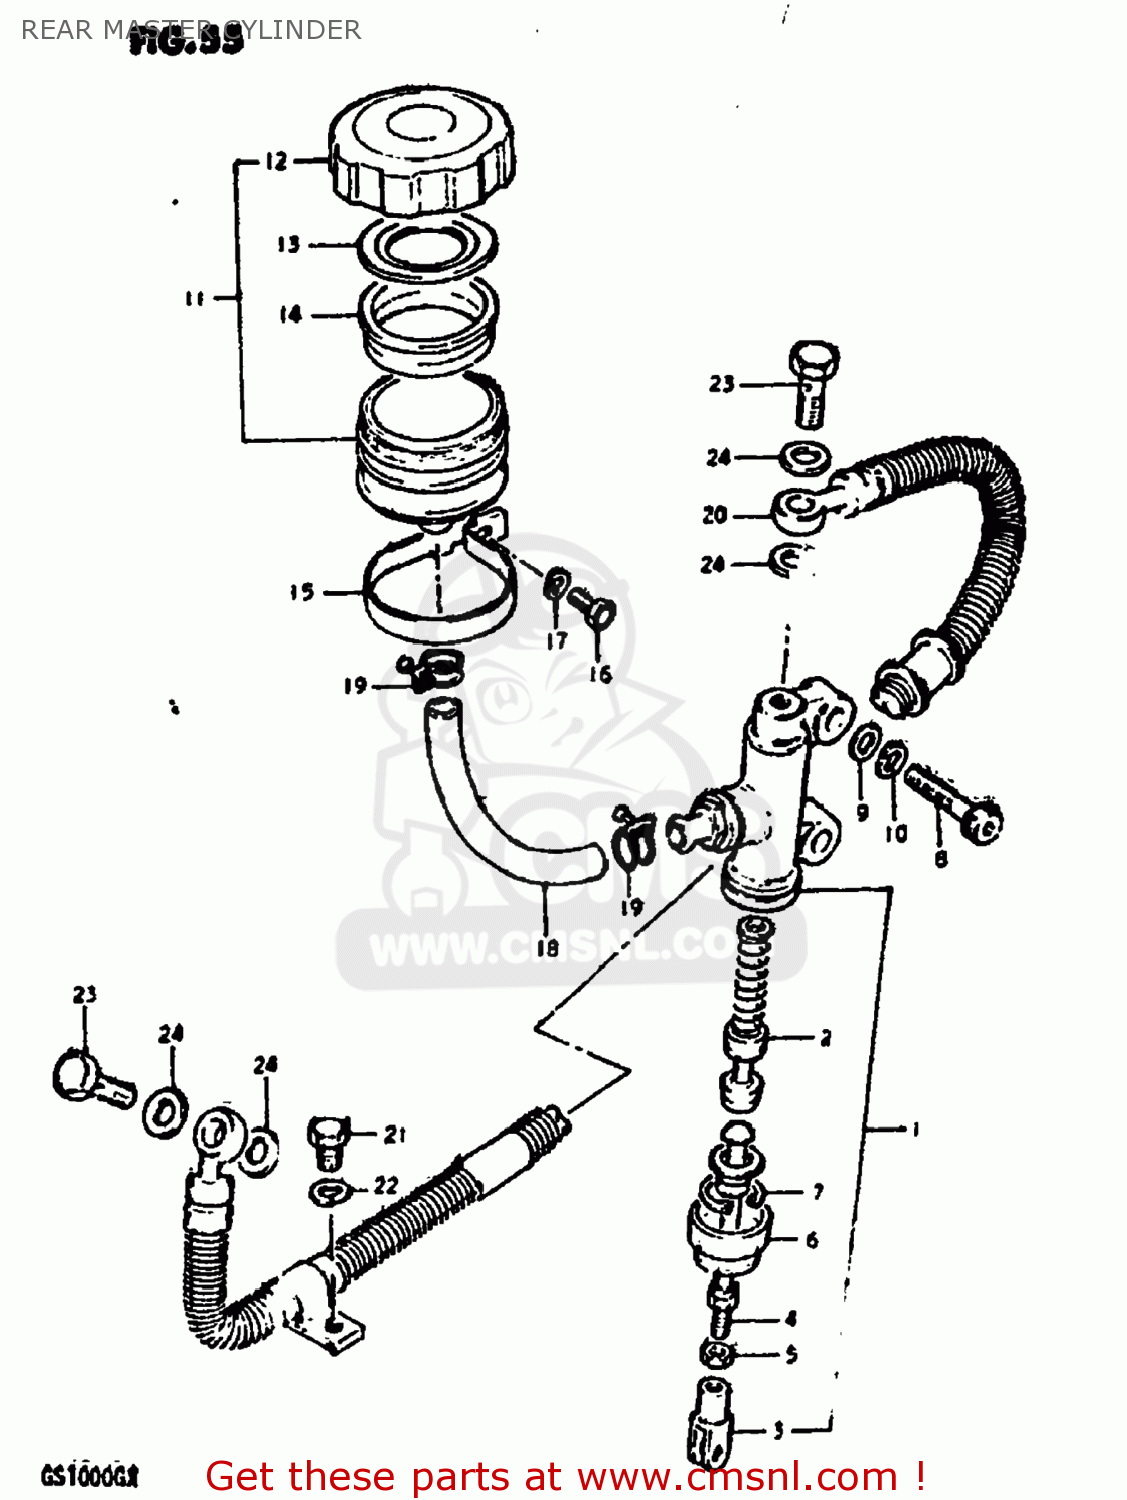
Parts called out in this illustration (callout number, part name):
1	CYLINDER ASSEMBLY,REAR MASTER
2	PISTON/CUP SET
3	YOKE
4	ROD,PUSH
5	NUT
6	BOOT
7	CIRCLIP
8	BOLT
9	WASHER
10	LOCK WASHER
11	TANK ASSEMBLY,RESERVOIR
12	CAP
13	PLATE,DIAPHRAGM
14	DIAPHRAGM
15	CLAMP
16	BOLT, UPPER
17	LOCK WASHER
18	HOSE,RESERVOIR TANK
19	CLAMP
20	HOSE,REAR BRAKE
21	BOLT
22	LOCK WASHER
23	BOLT,UNION
24	WASHER
